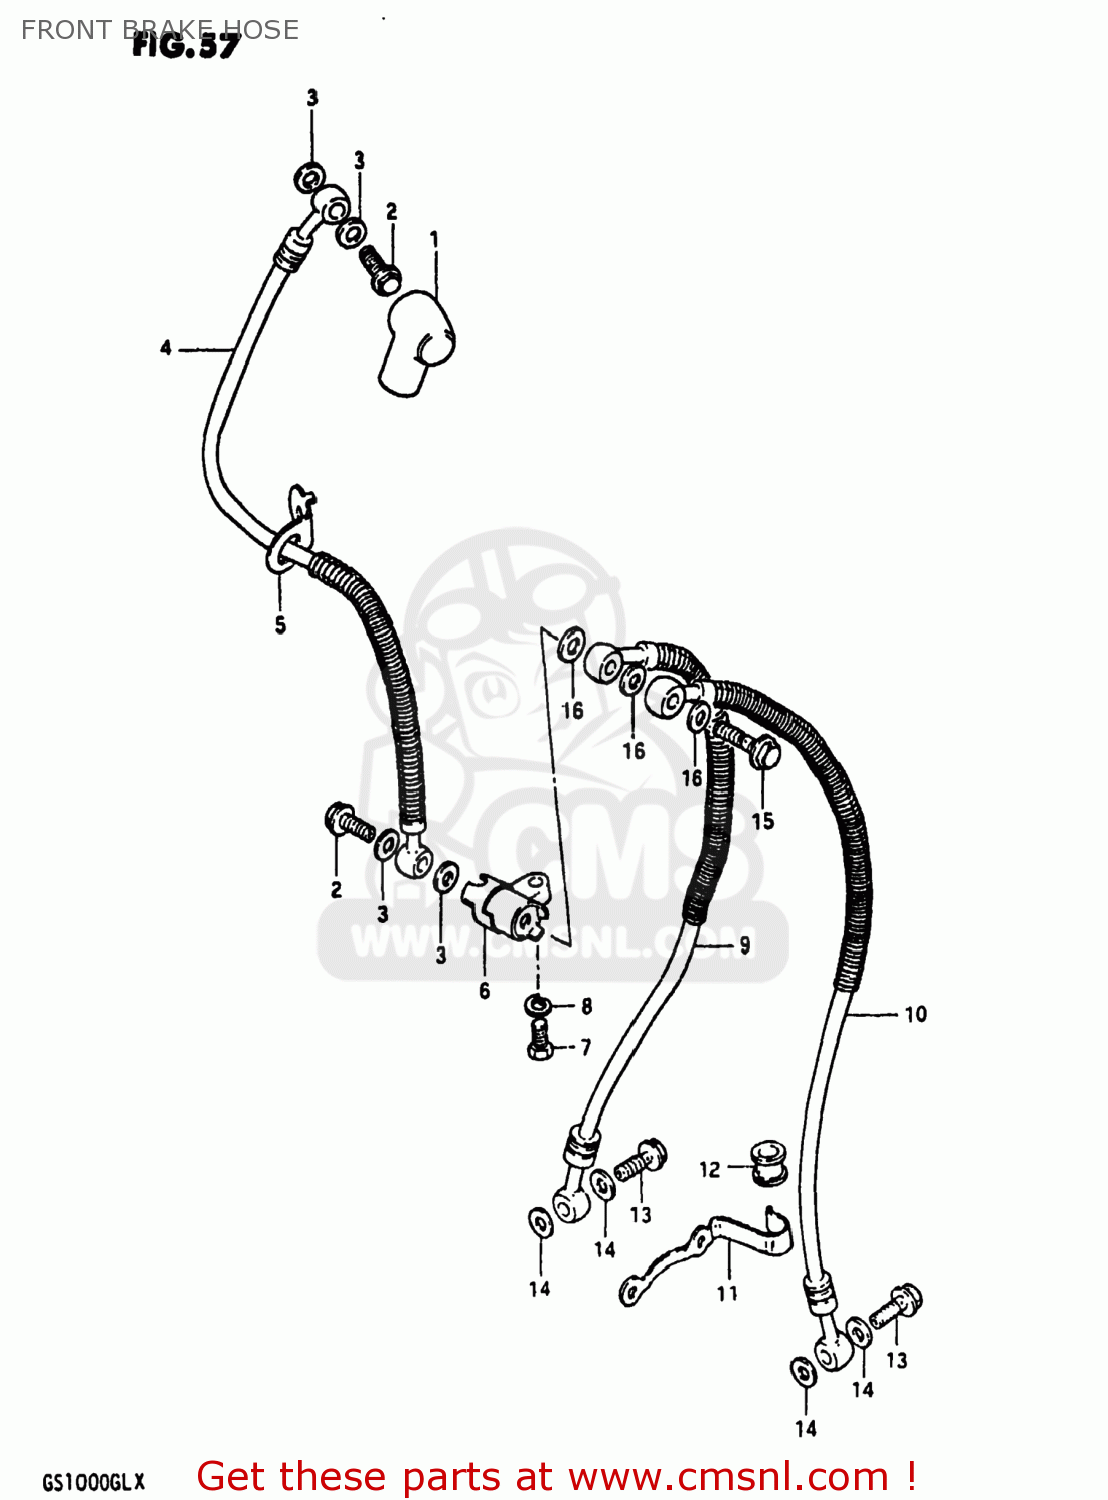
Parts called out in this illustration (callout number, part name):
1	BOOT,MASTER CYLINDER
2	BOLT,UNION
3	WASHER
4	HOSE,FRONT BRAKE NO.1
5	GUIDE,BRAKE HOSE
6	JOINT,BRAKE HOSE
7	BOLT
8	LOCK WASHER
9	HOSE,FR BRAKE NO.2,L
10	HOSE,FR BRAKE NO.2,L
11	GUIDE,BRAKE HOSE NO.2
12	BUSH,BRAKE HOSE GUIDE,NO.2
13	BOLT,UNION
14	WASHER
15	BOLT,UNION
16	WASHER
